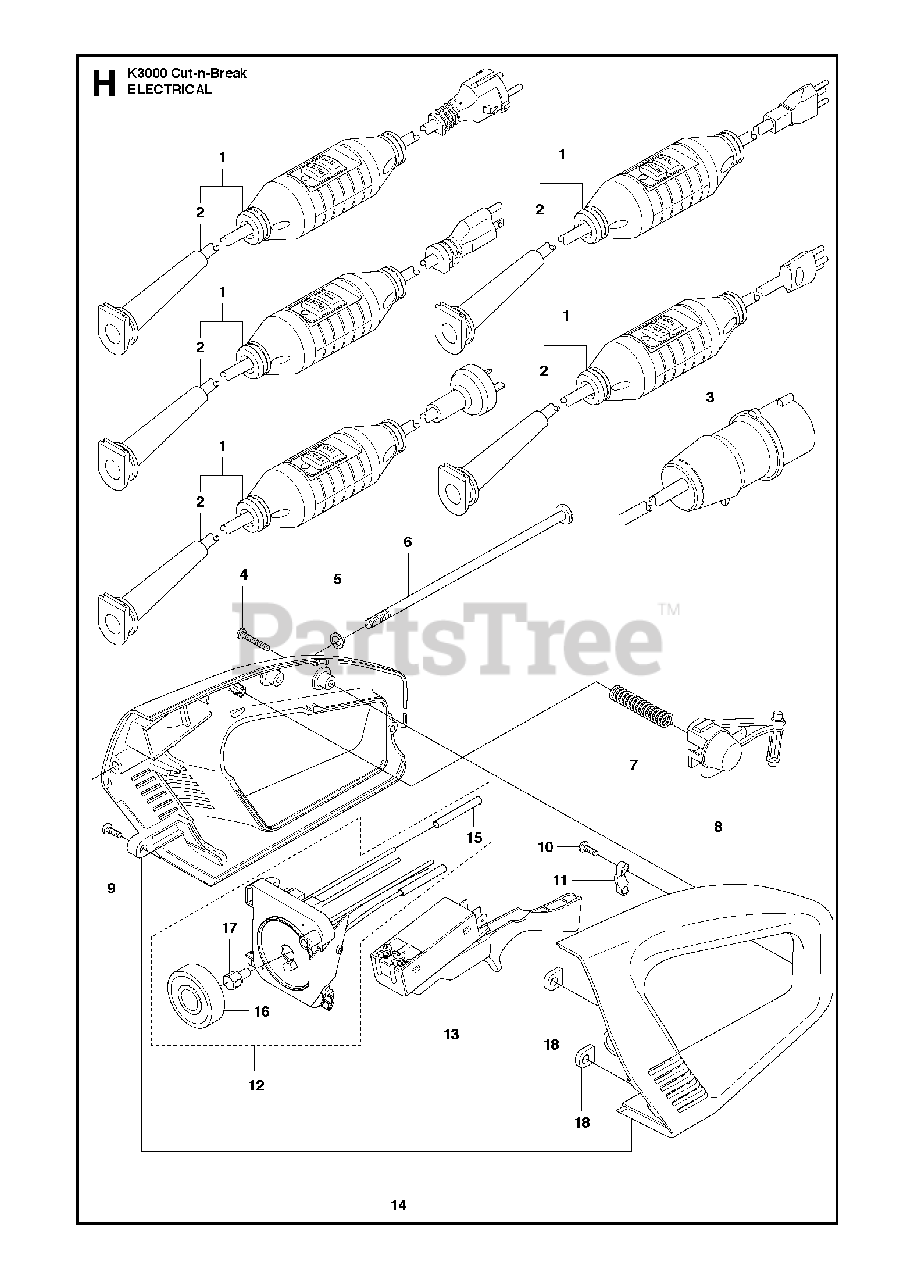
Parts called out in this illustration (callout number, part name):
1	CABLE110V JP, USA
1	CABLE230V BR, incl. 2
5	SPRING WASHER
7	SPRING
8	LOCKING BUTTON
9	SCREW CRPANM
14	HANDLE ASSY
